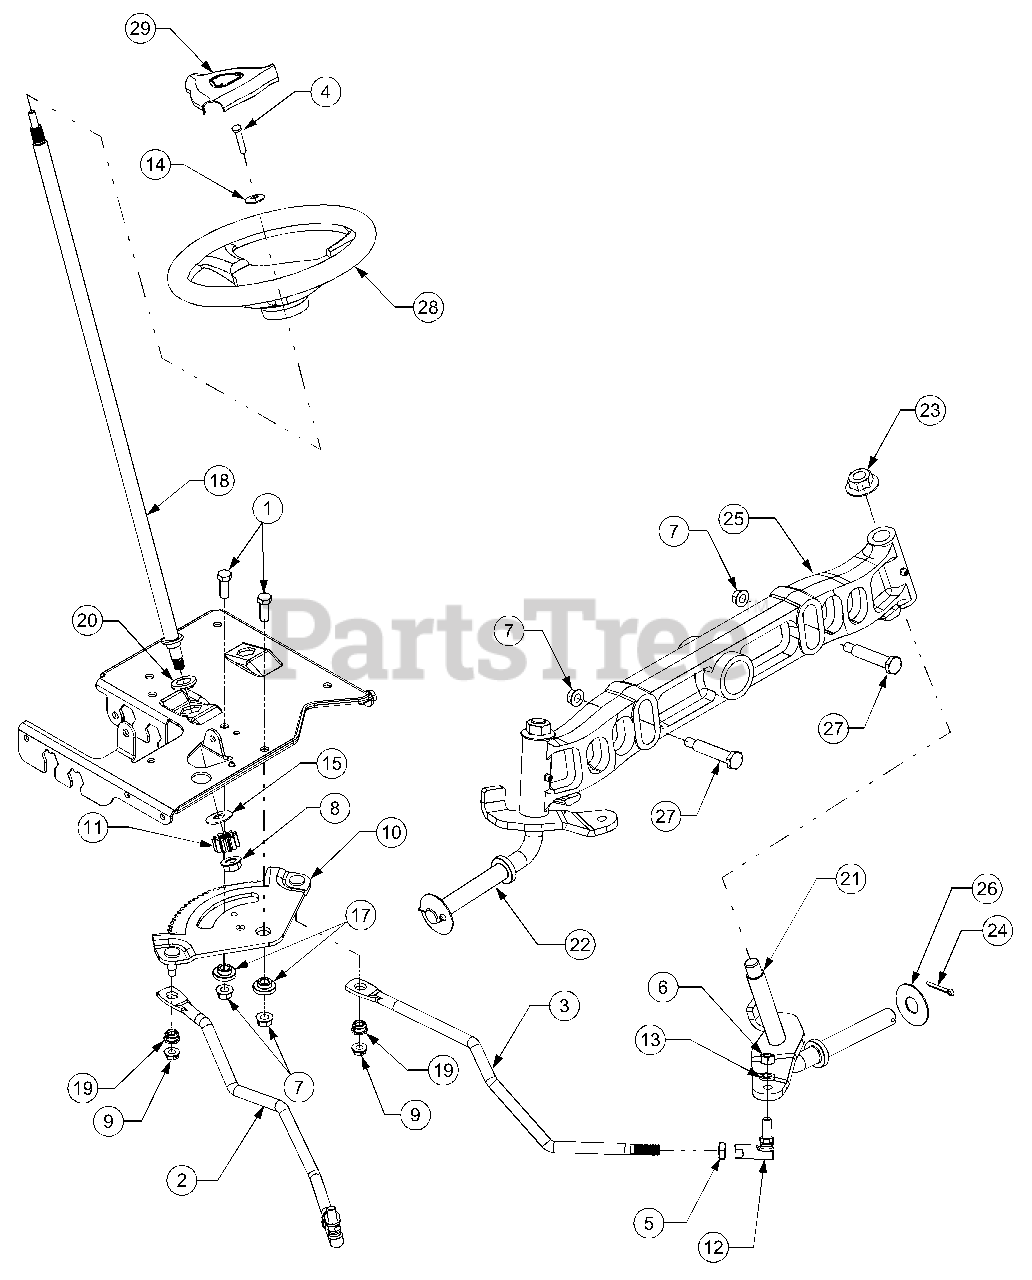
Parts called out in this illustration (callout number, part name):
1	Hex Cap Screw, 3/8-16, 1.00, Gr5, Std
2	Link, Drag, RH
3	Link, Drag, LH
4	Self-tapping Screw, 5/16-18 x .75
5	Nut, Jam, 7/16-20, Gr2
6	Nut, Hex, 3/8-24, Gr5
7	Nut, Nylon Lock, 3/8-16
8	Nut, Flange Lock, 7/16-20
9	Nut, Nylon Lock, 5/16-18
10	Gear, Steering, 11/90 Ratio
11	Gear, Pinion, Steering
12	Ball Joint, 7/16-20
13	Washer, Lock, 3/8, Regular Duty
14	Washer, Flat, .406 x .875 x .105
15	Washer, Flat, .510 x 1.120 x .060
16	Grease, Alvania Ep 2
17	Spacer, Shoulder, 1.00 x .38 x .38
18	Shaft, Steering, .625 OD x 25.00 Lg
19	Bushing, Plastic, .380 ID
20	Bearing, Hex Flange, 5/8
24	Pin, Cot, 5/32, 1.25
25	Axle, Pivot, Cast .750 Dia
26	Washer, Flat, .755 x 1.92 x .060
27	Spacer, Shoulder, .500 x 2.230, 3/8-16
28	Wheel, Steering, Three Spoke
29	Cover, Steering Wheel
